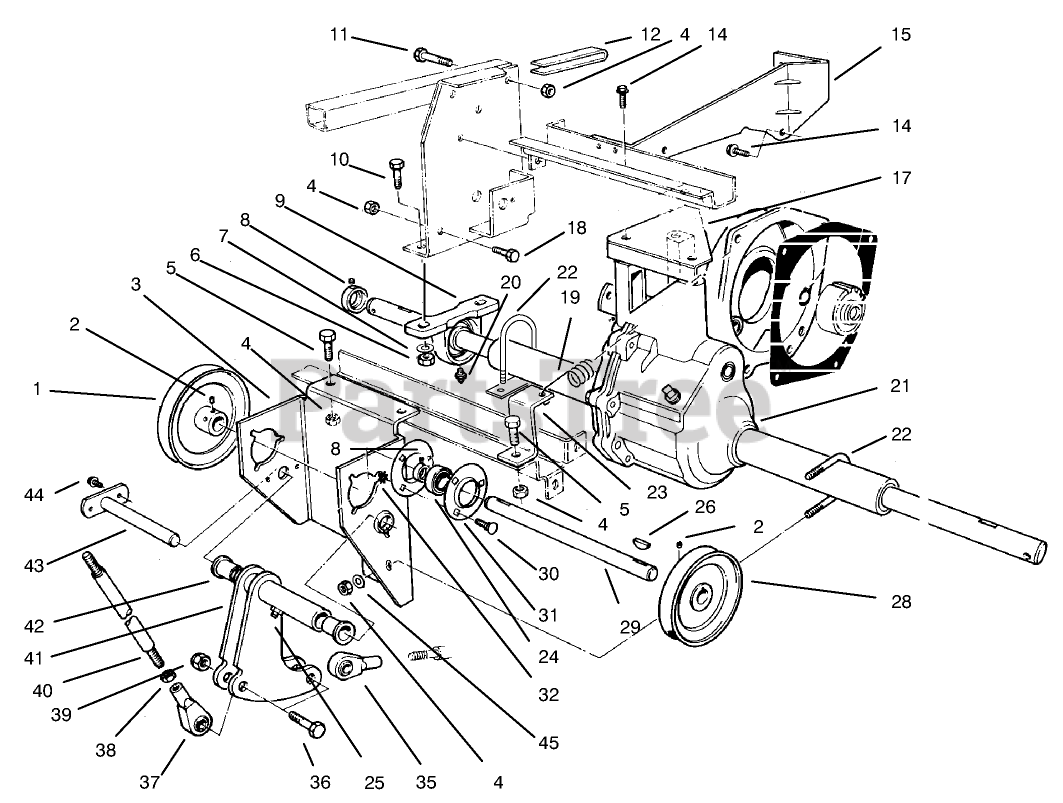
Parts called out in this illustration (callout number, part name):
1	JACKSHAFT OUTPUT PULLEY
2	SCREW-SET, SQH
3	Bracket-Jackshaft
4	NUT-LOCK, NI
5	SCREW-HH
6	NUT-LOCK, NI
7	WASHER-FLAT
8	SCREW-SET, HSH
9	BEARING - PILLOW BLOCK
10	SCREW-HH
11	SCREW-HH
12	TUBE SPACER
14	SCREW-HHF
15	Bracket-Transaxle
17	TRANSAXLE PLATE
18	SCREW-HH
19	SPRING-EXTENSION
20	FITTING-GREASE
21	Differential Assembly
22	U-BOLT
23	Bracket-Spring
24	BEARING-BALL
25	GREASE FITTING
26	KEY-WOODRUFF
28	JACKSHAFT INPUT PULLEY
29	JACKSHAFT
30	BOLT-CARR
31	FLANGE
32	NUT-KEPS
35	BALL JOINT LH
36	SCREW-HH
37	BALL JOINT RH
38	NUT-JAM
39	NUT-LOCK, NI
40	Rod-Steering
41	Bellcrank Assembly (Incl. Ref. #25 & 42)
42	BUSHING PM
43	Shaft-Bellcrank
44	SCREW-HHFTF
45	WASHER-PLAIN
